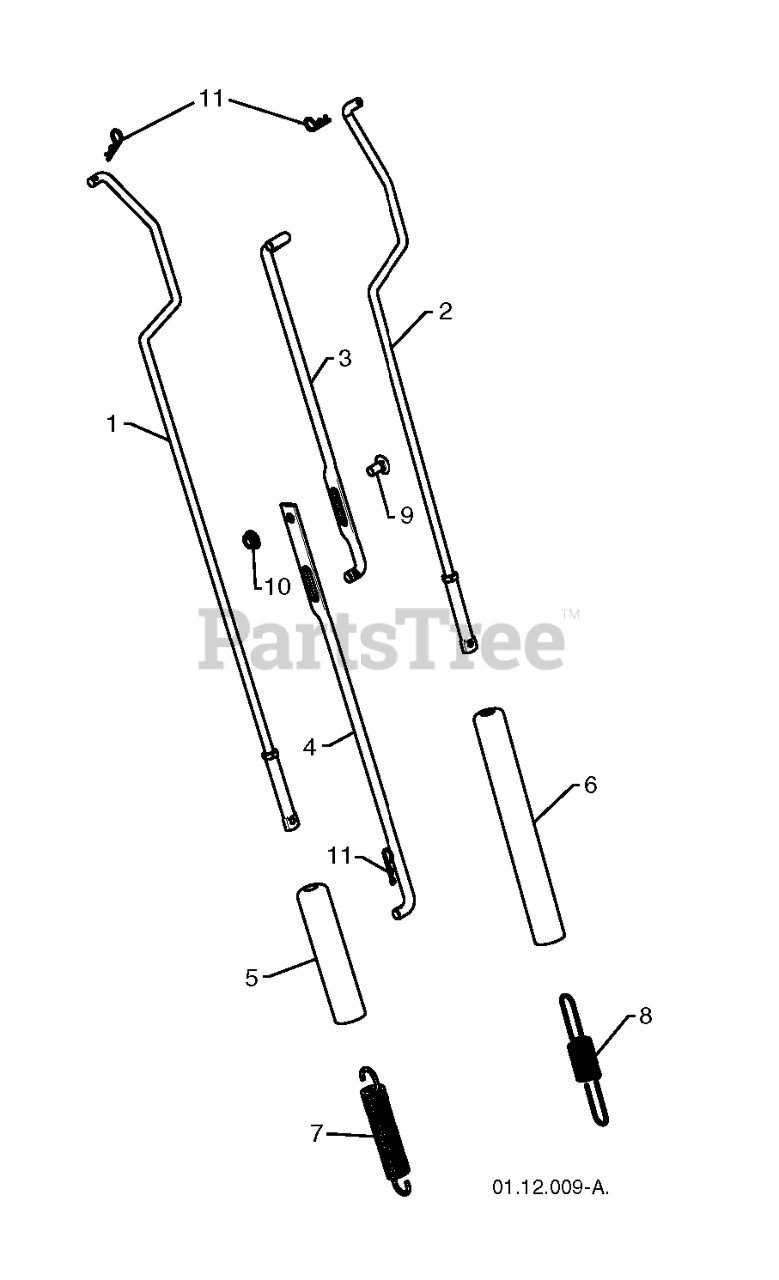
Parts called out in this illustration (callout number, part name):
1	ROD.ASM.IMPELLER.HYD
2	ROD.ASM.TRACTION.HYD.CLUTCH
3	ROD.SHIFTER.TOP.HYD.SNOW
4	ROD, LOWER, SPEED CONTROL
5	SLEEVE, SPRING
6	SLEEVE, SPRING
7	SPRING, AUGER CONTROL
8	SPRING, TRACTION DRIVE
9	BOLT
10	NUT.FLANGE.5/16
11	SPRING RETAINER
